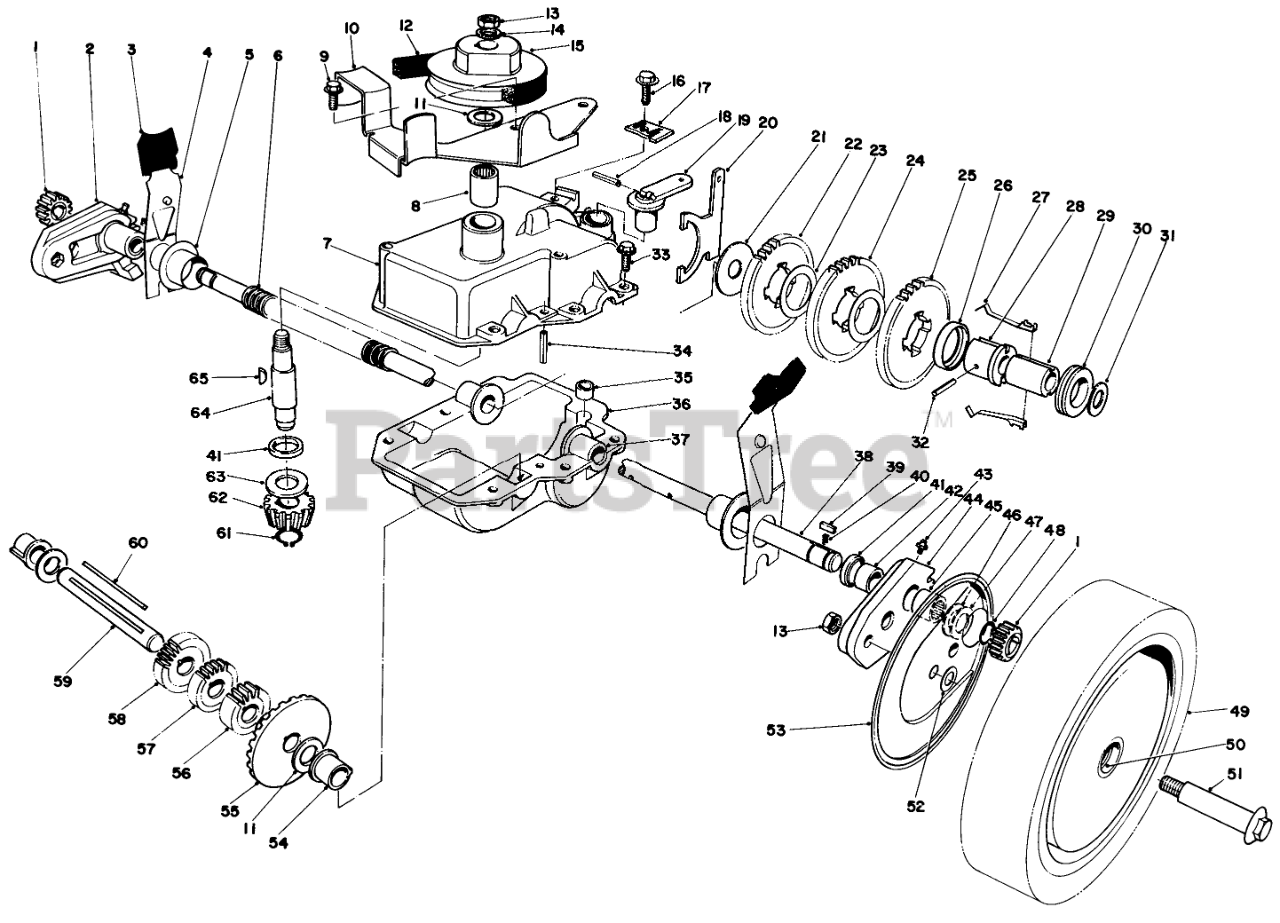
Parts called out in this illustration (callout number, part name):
1	Pinion
2	Pivot Arm Assembly-R.H. (Incl. Ref. #41-43 & 45)
3	KNOB-ARM
4	SPRING ARM ASM SP
5	CAP-END
6	CONDUIT-CONVOLUTED, SPLIT
7	Case-Upper
8	BEARING
9	SCREW
10	Bracket-Belt Guide
11	WASHER-THRUST
12	V-BELT
13	Nut
14	WASHER-FLAT
15	PULLEY
16	SCREW-HWHTF
17	Cable Clamp
18	PIN-COIL
19	LEVER-SHIFT
20	Shift Yoke
21	WASHER
22	GEAR-38T
23	WASHER
24	GEAR-42T
26	KEY RETAINER
27	Key
28	Body-Sleeve
29	SLEEVE
30	COLLAR-SHIFT
31	WASHER-PLAIN
32	PIN-SPRING
33	SCREW-HWH, THREAD ROLL
34	ROLL PIN 3/16 X 1 IN
35	BUSHING-YOKE
36	LOWER GEAR CASE CAST
37	Bushing-Output Shaft
38	Output Shaft
39	KEY RECTANGULAR
40	SPRING-COMPRESSION
42	BUSHING
43	FITTING-GREASE
44	Pivot Arm Assembly-L.H. (Incl. Ref. #41-43 & 45)
45	BEARING-ROLLER
46	Washer
47	THRUST WASHER
48	RING-RETAINING
49	Wheel, Tire & Gear Assembly (Incl. Ref. #50)
50	BUSHING
51	BOLT-WHEEL
52	WASHER
53	WHEEL COVER
54	BUSHING
55	BEVEL GEAR
56	GEAR-12T
57	GEAR-14T
58	GEAR-18T
59	INTERMEDIATE SHAFT
60	Key Square
61	RING-RETAINING
62	PINION-BEVEL
63	WASHER-THRUST
64	INPUT SHAFT
65	KEY-WOODRUFF
